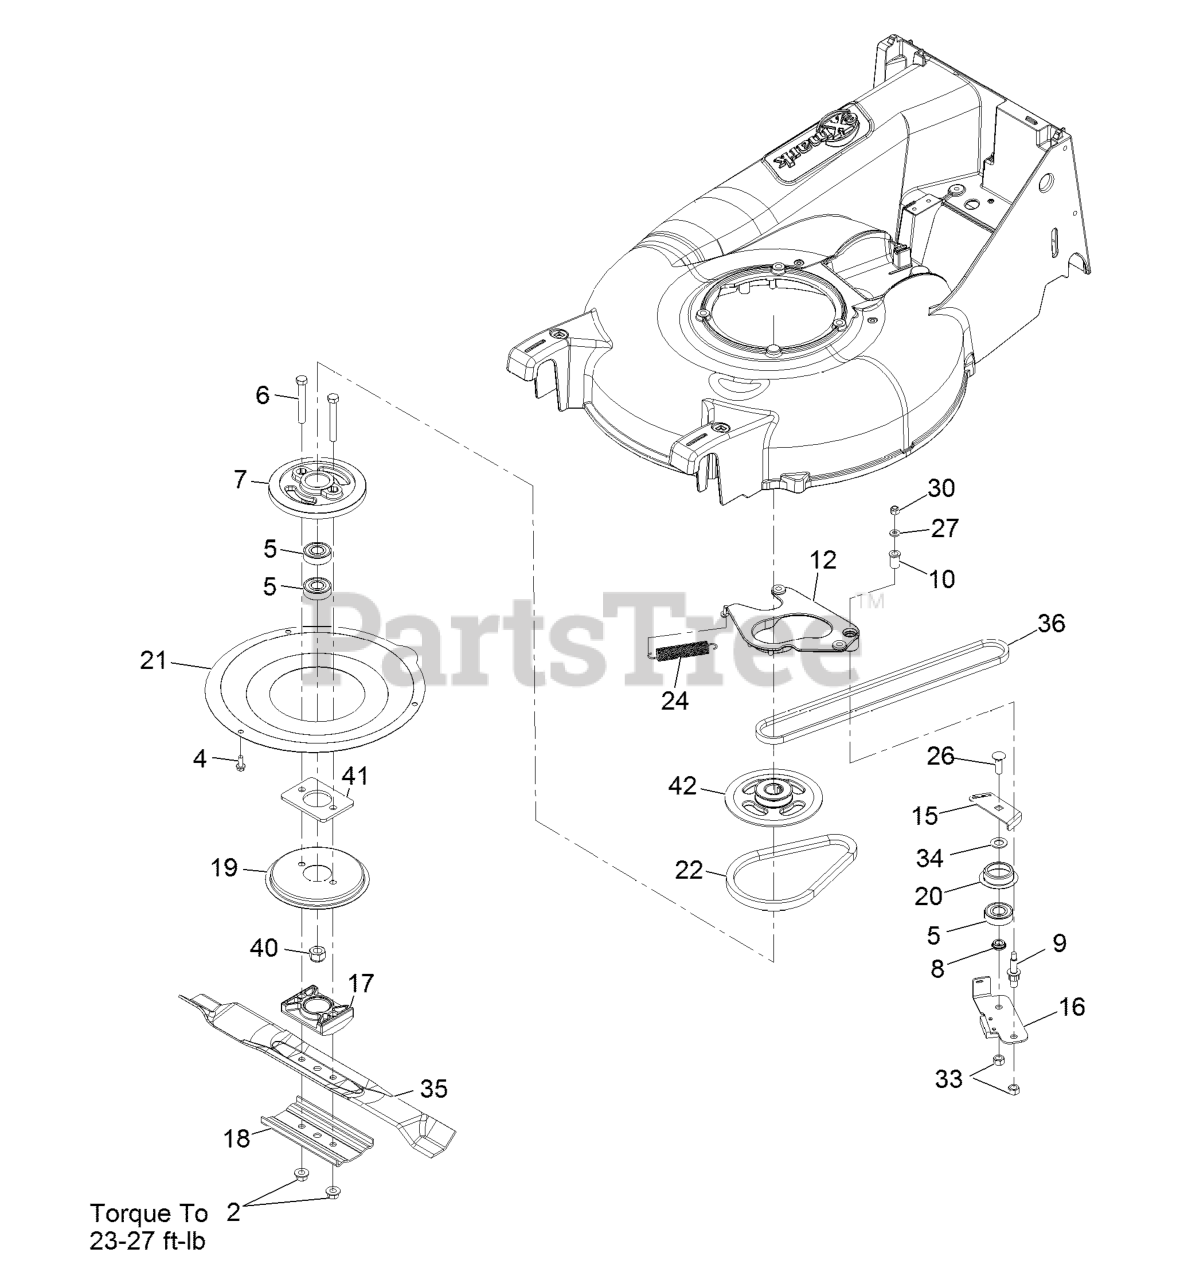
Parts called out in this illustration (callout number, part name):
2	Nut-Hex 3/8-24 Lock
4	SCREW-HWH
6	SCREW-HH
8	SPACER-BEARING
9	BOLT-SHOULDER
10	BUSHING
12	PLATE,ANCHOR
15	PLATE-GUIDE
17	SUPPORT-BLADE
18	SUPPORT-BLADE
19	DISC
20	RETAINER-BELT
21	COVER-BBC
22	BELT
24	SPRING-TENSION, BRAKE
26	SCREW-CARR
27	WASHER-FLAT
30	NUT-LOCK, NI
33	LOCKNUT
34	SPACER
36	BELT,3L P21 DRIVE
40	NUT-HEX
